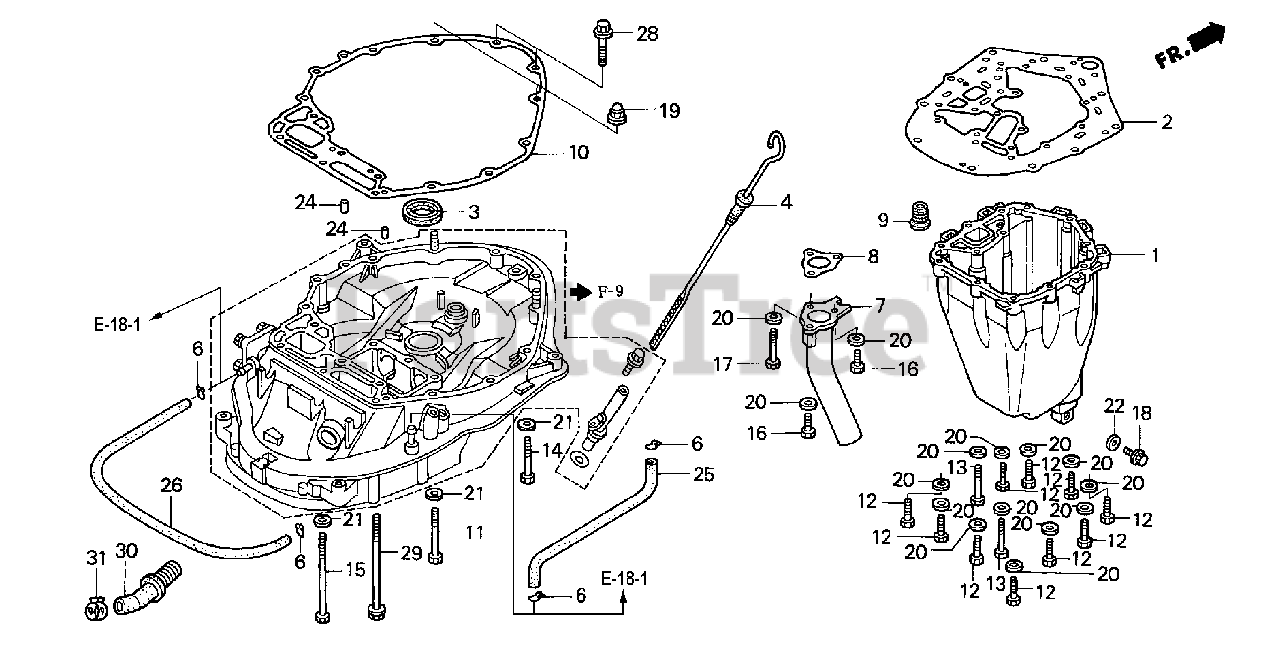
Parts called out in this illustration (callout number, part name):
1	PAN, OIL *TGRAY* (GRAY)
2	GASKET, OIL PAN
3	RUBBER, OIL PUMP
4	DIPSTICK, OIL
6	CLIP, TUBE
8	GASKET, EX. PIPE
9	GROMMET, WATER TUBE
10	GASKET, MOUNT CASE
11	BOLT, HEX. (10X60)
12	BOLT, HEX. (8X35)
13	BOLT, HEX. (8X55)
14	BOLT, HEX. (10X47)
15	BOLT, HEX. (10X110)
16	BOLT, HEX. (8X25)
17	BOLT, HEX. (8X65)
18	BOLT, DRAIN PLUG
19	NUT, FLANGE CAP (10MM)
20	WASHER, PLAIN (8MM)
21	WASHER, PLAIN (10MM)
22	WASHER, DRAIN PLUG (12MM)
24	PIN, DOWEL (6X10)
25	BULK HOSE, VACUUM (7X3000) (7X550)
26	BULK HOSE, VACUUM (7X3000) (7X690)
28	BOLT, FLANGE (10X45)
29	BOLT, FLANGE (10X130)
30	TUBE SET, OIL
31	CLAMP, TUBE (D29)
